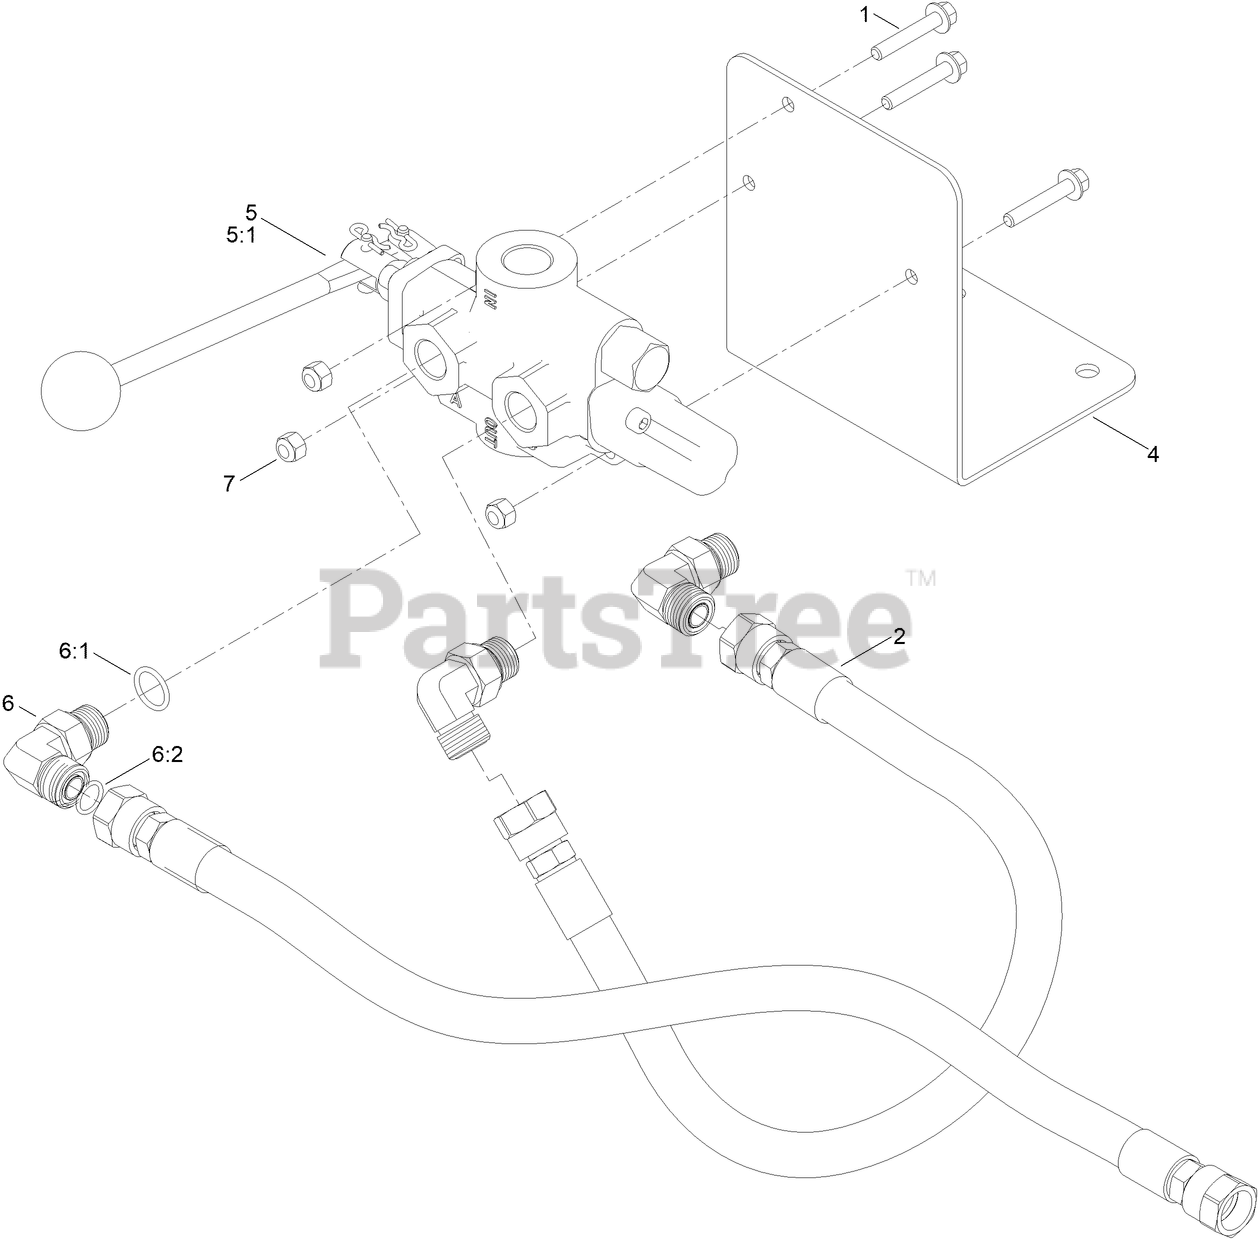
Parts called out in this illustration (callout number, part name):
1	SCREW-HHF
2	HOSE ASM-HYD
4	BRACKET-VALVE
5	VALVE-CONTROL
5:1	KIT-HANDLE, VALVE
6	FITTING-ELBOW, 90 DEG
6:1	O-RING
6:2	O-RING
7	NUT-LOCK, NI
